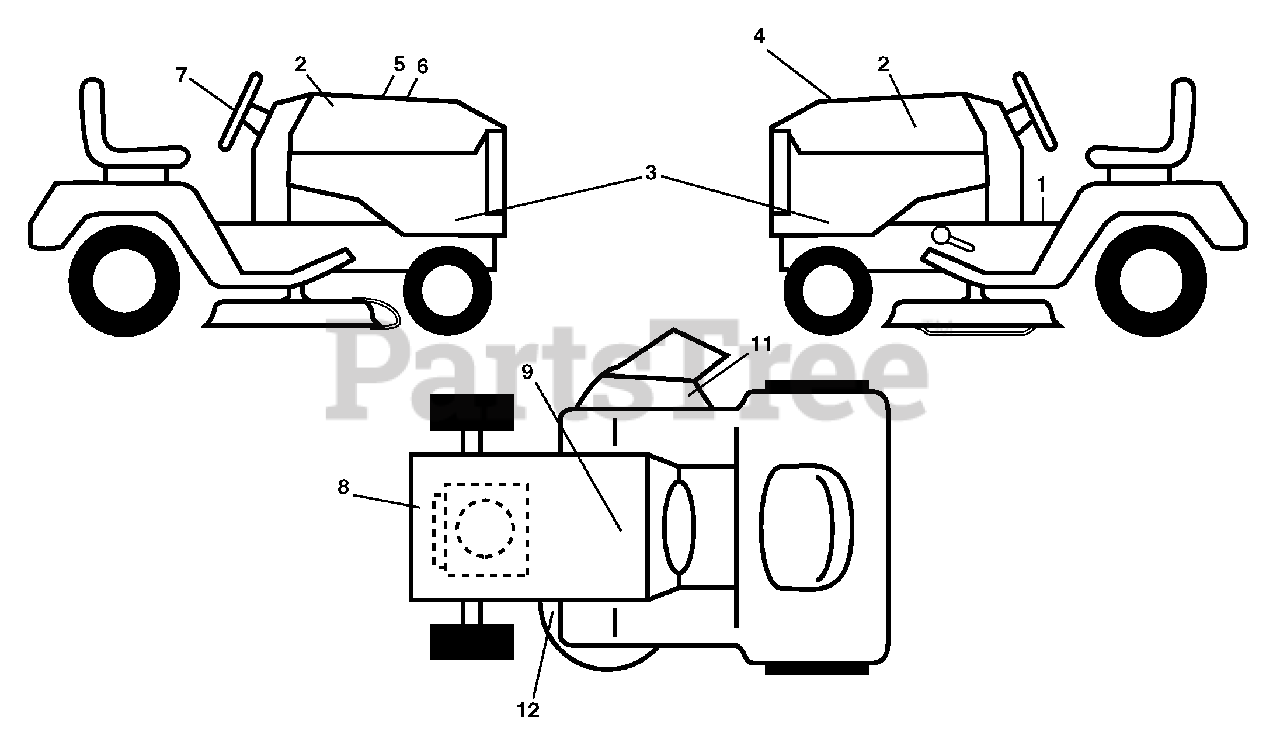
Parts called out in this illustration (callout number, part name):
1	Decal, Operators
2	Decal, Hood
3	Decal, Hood Panel SD
4	Decal, Hood Top Insert
5	Decal, Customer Respons.
6	Decal, Replacement
7	Decal, Steering Wheel
8	Decal, Eng. HP
9	Decal, Battery Dnge/Poi
11	Decal, Warning
12	Decal, Mower V-Belt Schematic
